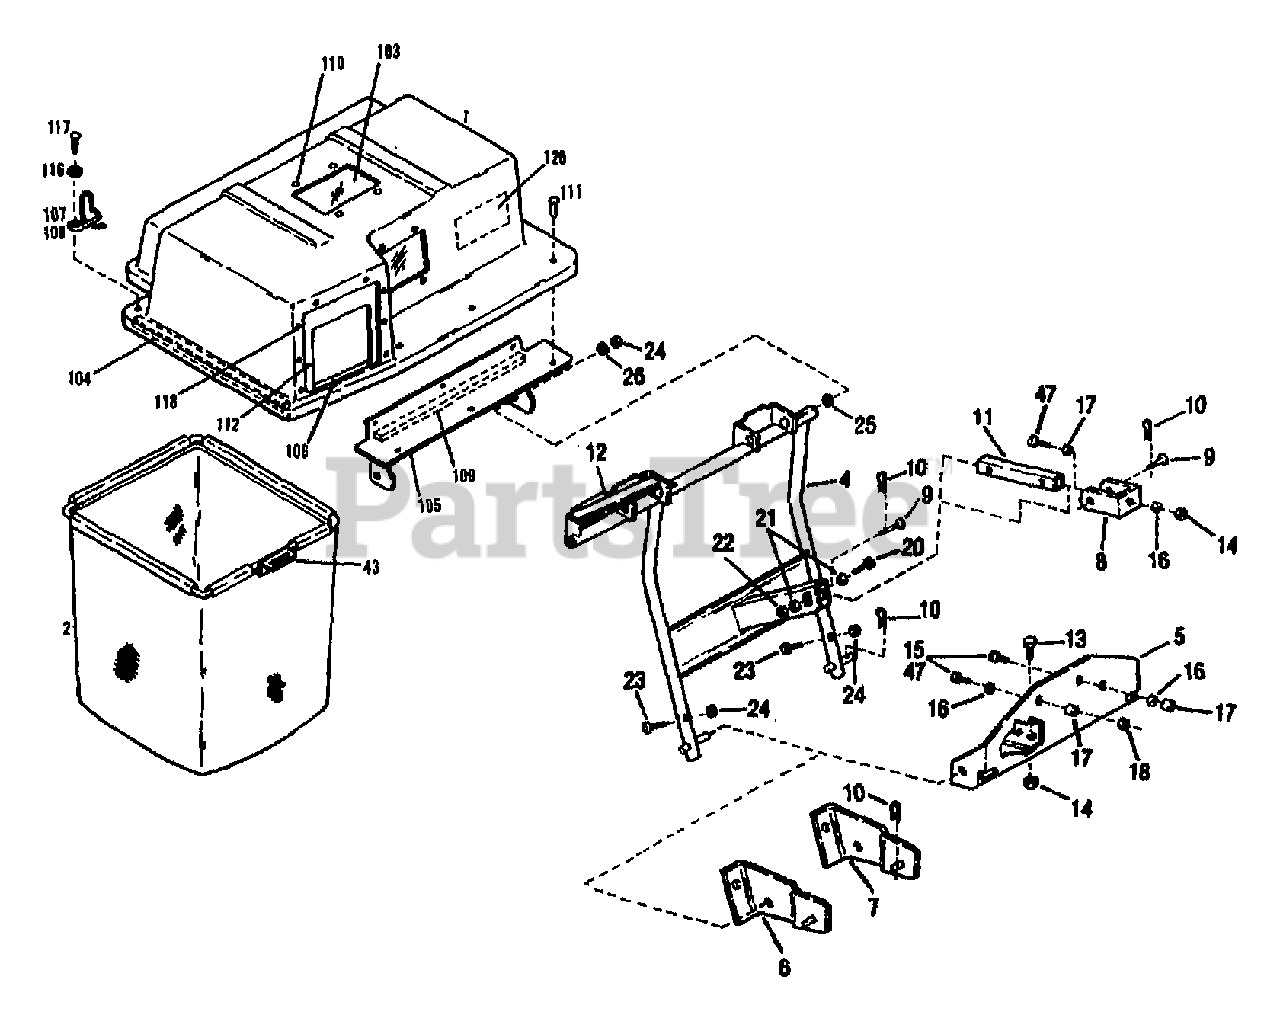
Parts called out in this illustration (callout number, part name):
1	ASSM-CVR GRASS BAG
2	ASSM-GRASS BAG
4	SUPPORT-GRASSBAG
5	PLATE-MOUNTING GRASSBAG
6	ARM-EXTENSION RH
7	ARM-EXTENSION LH
8	BRKT-HITCH
9	PIN-CLEVIS .5X2.0 ZP
10	CLIP-HAIRPIN .07 DIA
11	ADAPTER-ARM
12	SEAL-COVER 9.5"
13	SCR-HH 3/4-10 X 2.00
14	NUT-H/LK 3/4-10
15	SCR-HH 1/2-13X1.75 G5 ZP
16	WASHER-LK .5
17	SPACER-.75X.531X.89
18	NUT-HEX JAM 1/2-13
20	SCR-HH 1/2-13X2.25 G5 ZP
21	WASHER-1.06X.531X.1 ZP
22	NUT-TOP LOCK 1/2-13 ZP
23	SCR-HH 5/16-18X1.75
24	NUT-TOP/LK 5/16-18 ZP
25	WASHER-.87X.34X.06 NYLON
26	WASHER-FLAT 5/16 SAE
43	ASSM-FRAME GRASSBAG
47	SCR-HH 1/2-13X1.0 G5 ZP
103	WINDOW
104	SEAL-COVER
105	ASSM-HINGE SUPPORT
107	COVER-LOCK RH
108	COVER-LOCK LH
109	SEAL-COVER
110	RIVET-POP
111	RIVET-POP 3/16"DIA
112	GASKET-CHUTE
116	WASHER-.88X.2X.059
117	RIVET-POP 3/16X1/2
118	RIVET-POP .125
120	DECAL-INST
